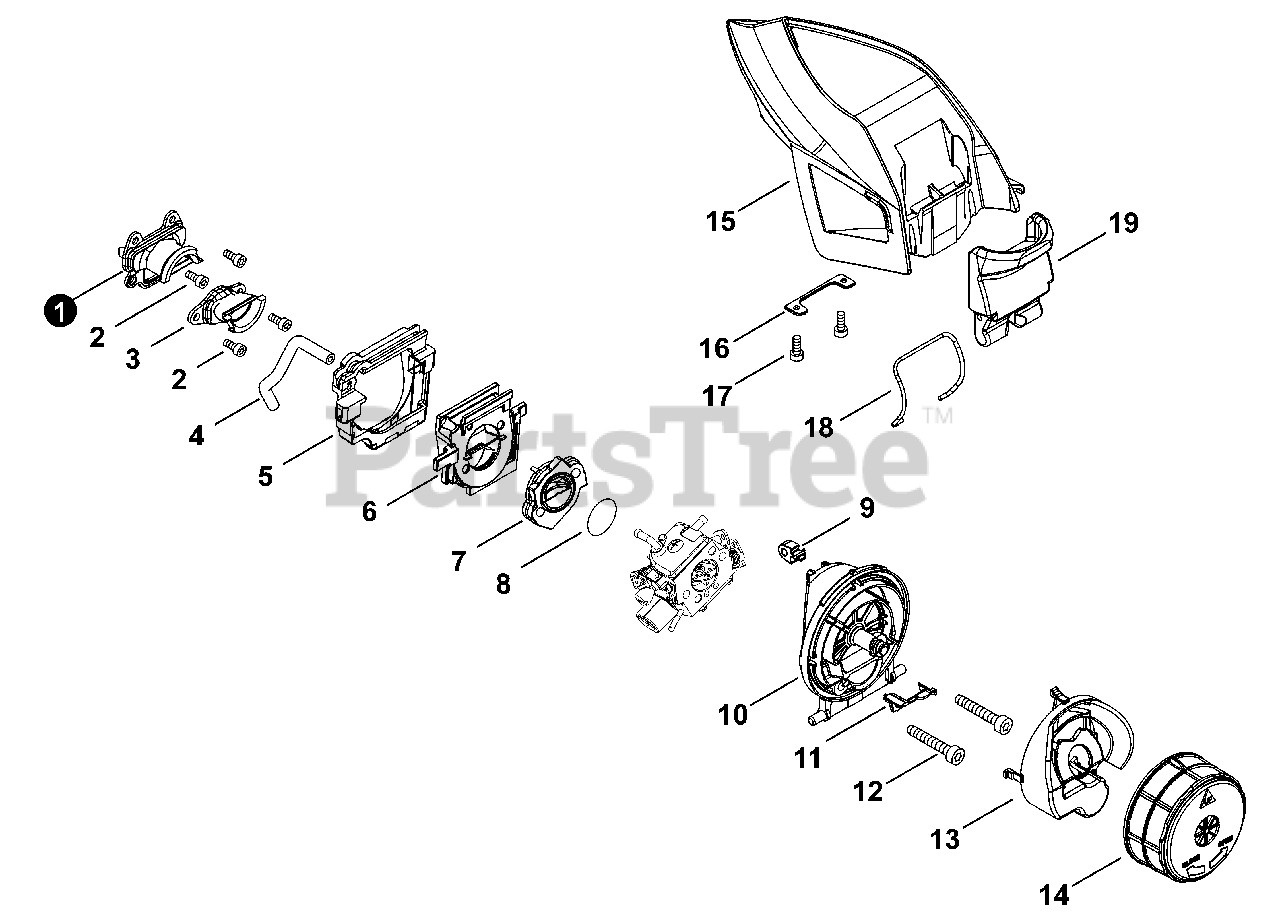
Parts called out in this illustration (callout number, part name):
1	BELLOWS, INTAKE
2	BOLT, TORX 4×12
3	BELLOWS, INTAKE
4	PIPE 3×6×90 MM
5	CUSHION
6	INSULATOR, INTAKE
7	INSULATOR, INTAKE
9	CUSHION
10	CASE, AIR FILTER
11	DUCT, AIR
12	BOLT, TORX 5×55
13	DUCT, AIR
14	FILTER, AIR
15	COVER, AIR FILTER
16	SPRING, FLAT
17	BOLT, TORX 4×12
18	RETAINER
19	LATCH, COVER
